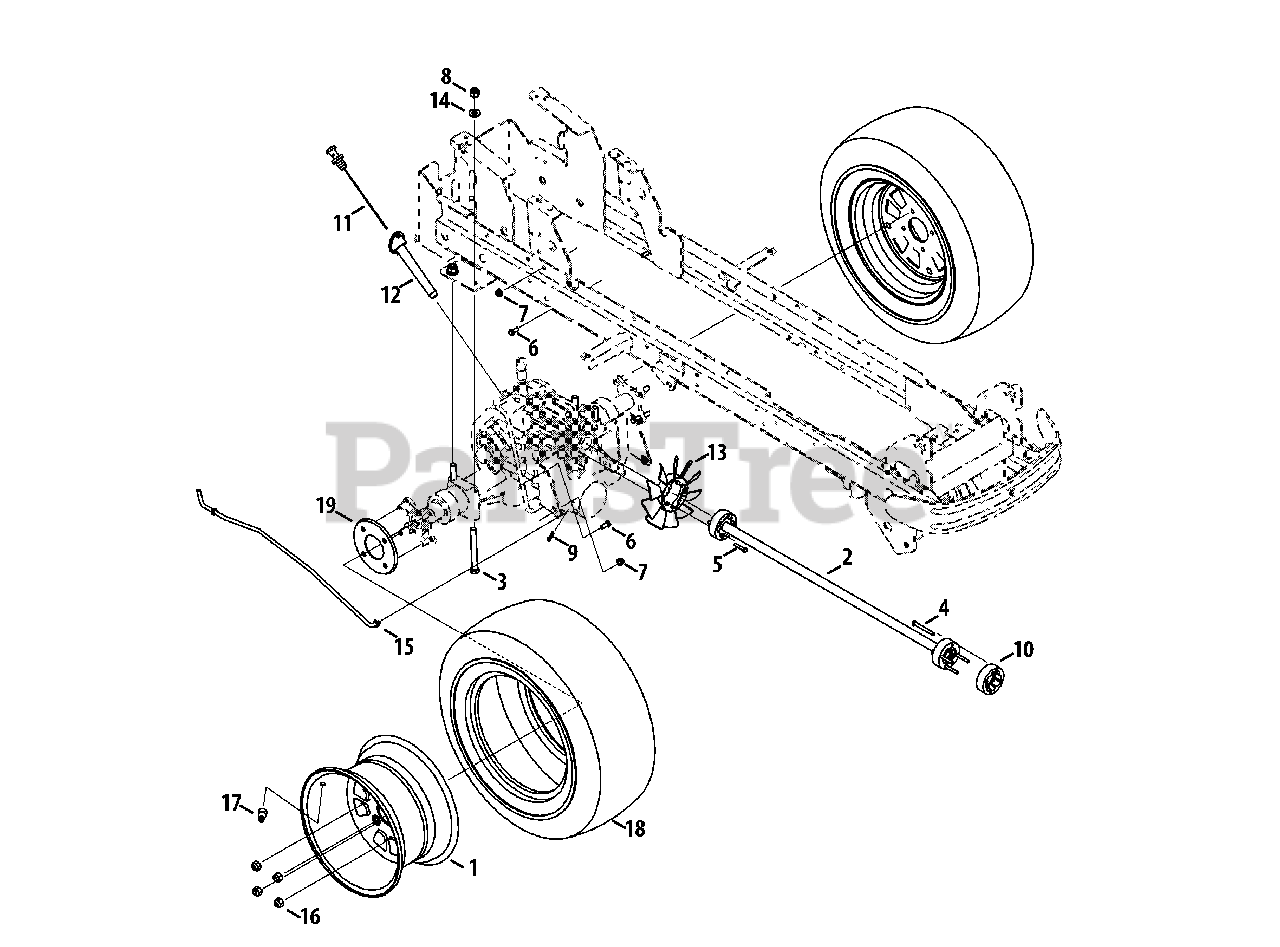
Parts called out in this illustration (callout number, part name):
1	Rim Assembly, 12.0 x 7.0
2	Shaft Assembly, 30.55
3	Hex Screw, 1/2-20 x 4.50
4	Hex Screw, 1/4-20 x 2.50
5	Hex Screw, 1/4-20 x 1.25
6	Hex Screw, 5/16-18 x .75
7	Flange Lock Nut, 5/16-18
8	Hex Lock Nut, 1/2-20
9	Bow-Tie Cotter Pin, 72
10	Drive Shaft Adapter
11	Transaxle Dipstick
12	Dipstick Holder
13	Pump Fan, 7.0
14	Flat Washer, .531 x 1.062 x .134
15	Hydro Relief Lever
16	Lug Nut, 7/16-14
17	Tubeless Air Valve
18	Tire, 23.0 x 10.5 x 12
